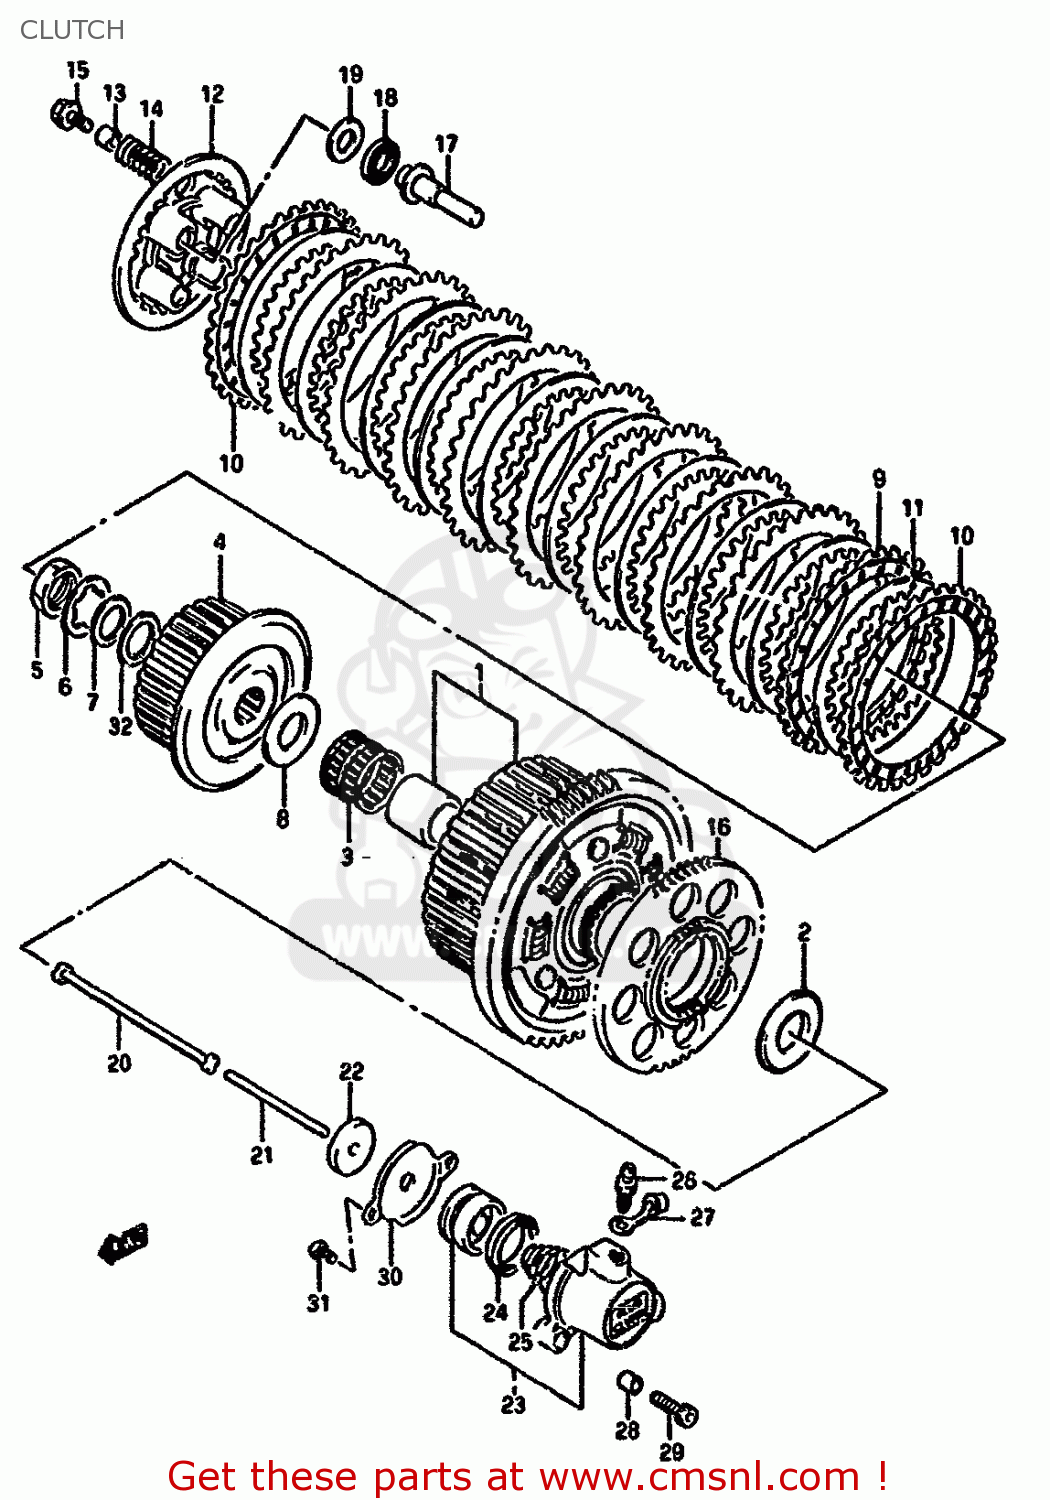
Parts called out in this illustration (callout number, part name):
1	GEAR ASSEMBLY,PRIMARY DRIVE
2	WASHER(25X54X2.5)
3	BEARING(35X40X35.8)
4	HUB,CLUTCH SLEEVE
5	NUT
6	WASHER,LOCK
7	WASHER
8	WASHER(25X50X2.5)
9	PLATE,CLUTCH DRIVE NO.1 (NAS)
10	PLATE,CLUTCH DRIVE NO.2 (NAS)
11	PLATE,CLUTCH DRIVEN (NAS)
12	DISC,CLUTCH PRESSURE
13	SPACER(6.2X12X14)
14	SPRING
15	BOLT
16	GEAR,GENERATOR DRIVE
17	PIECE,CLUTCH PUSH
18	BEARING(15X28X2)
19	WASHER
20	ROD,CLUTCH
21	ROD,CLUTCH PUSH,L
22	SEAL,OIL(6X34X5.5)
23	CYLINDER,CLUTCH RELEASE
24	CUP,CLUTCH CYLINDER
25	SPRING,CLUTCH CYLINDER
26	BLEEDER
27	CAP,BLEEDER
28	PIN
29	BOLT
30	PLATE,CLUTCH PUSH ROD
31	SCREW
32	SHIM
